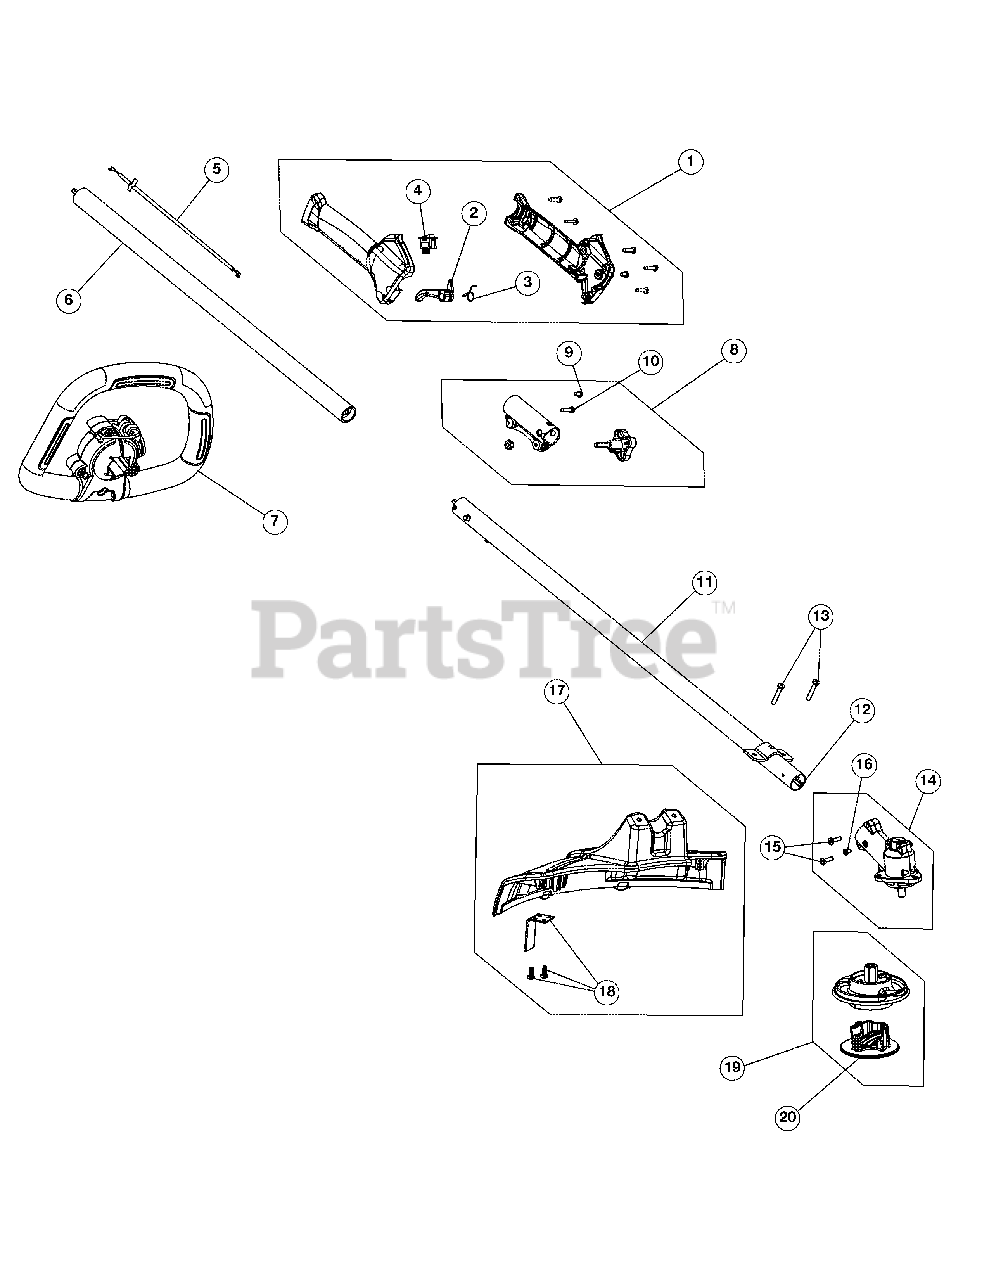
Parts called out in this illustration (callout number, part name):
1	Throttle Housing Assembly (Incl. 2-4)
2	Throttle Trigger
3	Throttle Trigger Spring
4	Switch Assembly
5	Throttle Cable Assembly
6	Upper Drive Shaft Assembly
7	Handle
8	Split Boom Coupler (Incl. 10-11)
9	Coupler Anti-Rotation Screw
10	Coupler Bolt
11	Lower Drive Shaft Housing
12	Lower Flexible Drive Shaft
13	Shield Mount Screw Assembly
14	Gearbox Assembly (Incl. 16 & 17)
15	Gearbox Screw
16	Gearbox Anti-Rotation Screw
17	Shield Assembly (Incl. 19)
18	Blade Assembly
19	Cutting Head Assembly (Incl. 21)
20	Cutting Head Cap
